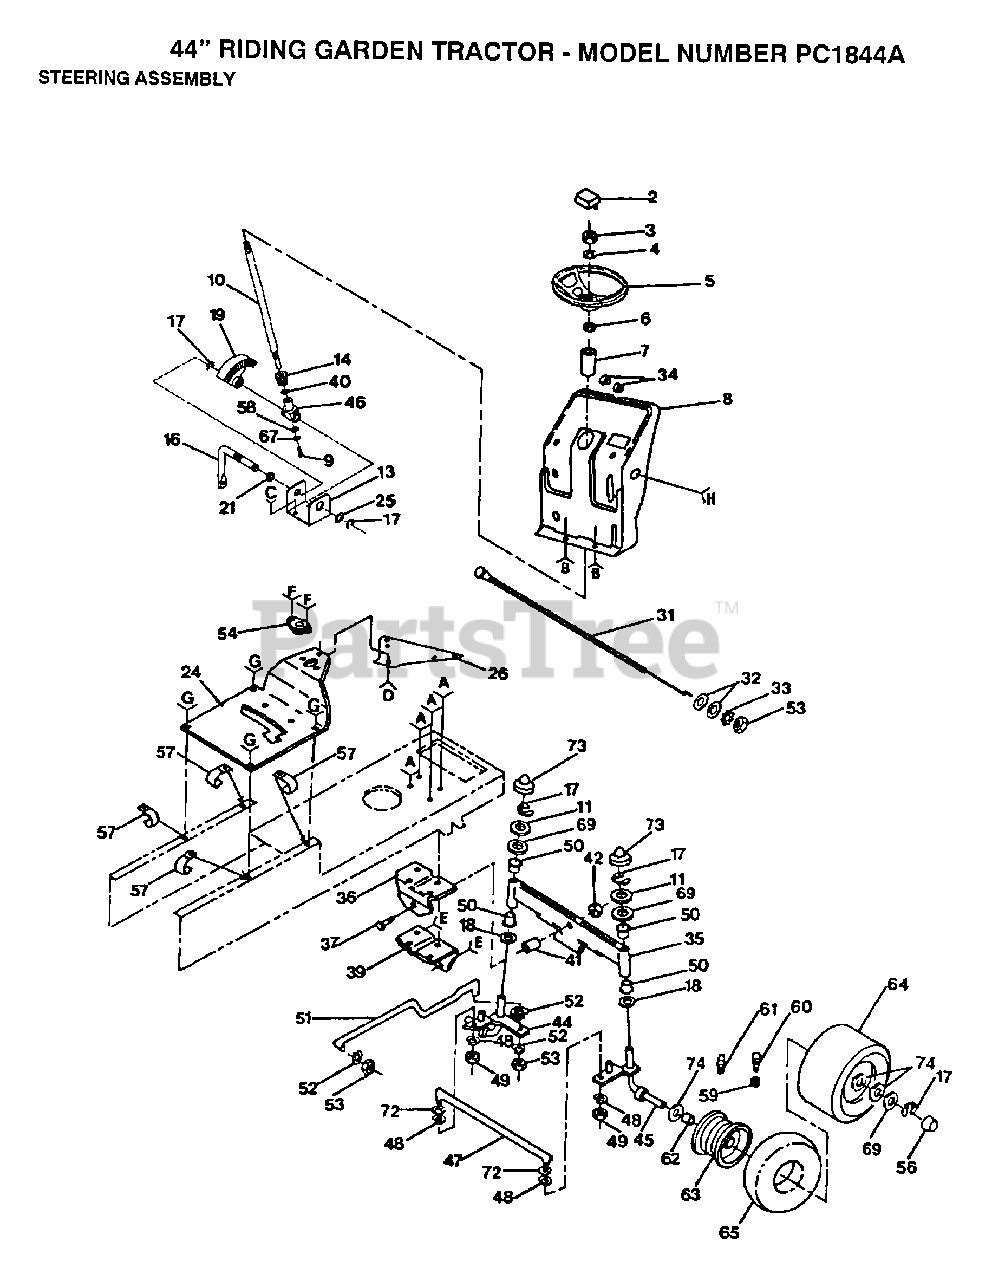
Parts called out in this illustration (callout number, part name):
2	INSERT-WHEEL LT
4	WASHER
6	ADAPTER LT
7	SLEEVE LTV
9	"SCREW,SPECIAL"
11	WASHER
13	"BRKT,STEERING"
14	"GEAR,PINION"
15	SCREW SPECIAL
17	RING
18	WASHER .T
21	NYLINER T
22	SCREW
25	WASHER .T
27	BOLT
32	WASHER
33	LOCKWASHER
34	PLUG-DASH T
35	FRONT AXLE
36	SUPPORT-SADDL T
37	BOLT LT
38	SCREW LT
39	SUPPORT.SADDLE.FT
40	THRUST WASHER
41	BEARING
42	"NUT-LOC,FLANGE LT"
43	SCREW LT
44	SPINDLE-LH LT
46	SUPPORT.SHAFT
48	LOCKWASHER
49	NUT.LOCK.5/16-24
50	COL. SRTG. BEAR.
52	LOCKWASHER
56	HUB CAP
57	CLIP T
59	VALVE CAP
60	VALVE STEM LT
61	FITTING LT
62	"FLANGE, BEARING"
65	TUBE.5.3/4.5/6
66	BOLT
67	LOCKWASHER
68	NUT
69	WASHER
70	SCREW
72	WASHER M
73	CAP
74	WASHER
